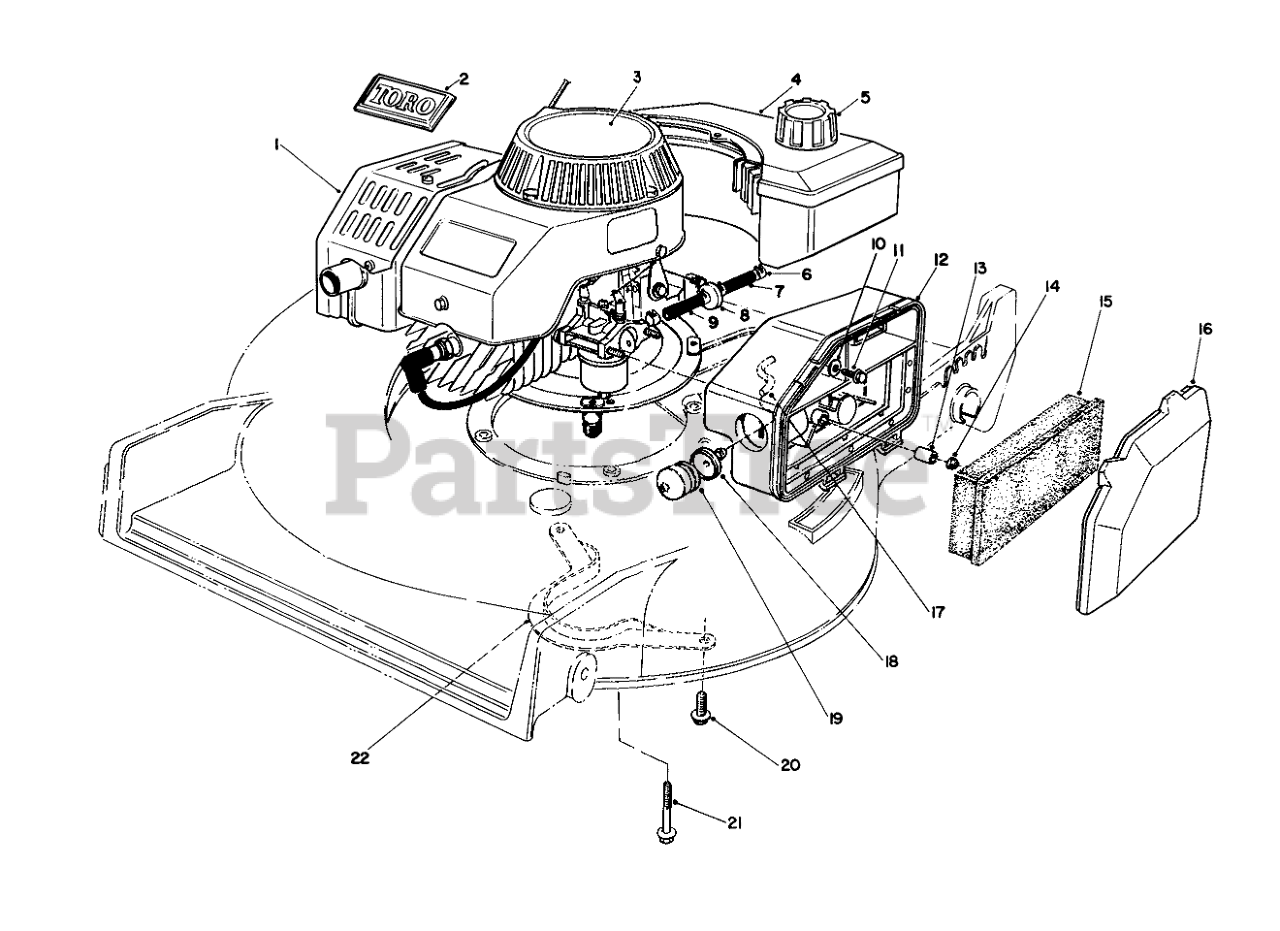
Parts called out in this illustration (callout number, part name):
1	Engine
2	TORO LOGO PLT
3	DECAL
4	Gas Tank Assembly
5	GAS CAP ASM
6	CLAMP-FUEL LINE
7	HOSE-FUEL
8	FILTER-FUEL
9	HOSE-FUEL
10	WASHER-FLAT
11	SCREW-HH
12	BODY-AIR CLEANER
13	SPACER
15	ELEMENT-AIR CLEANER
16	COVER-AIR CLEANER
17	HOSE-PRIMER
18	BODY-PRIMER
19	Bulb Primer
20	SCREW-HHF
21	SCREW-HHF
22	BBC BELT GUIDE
